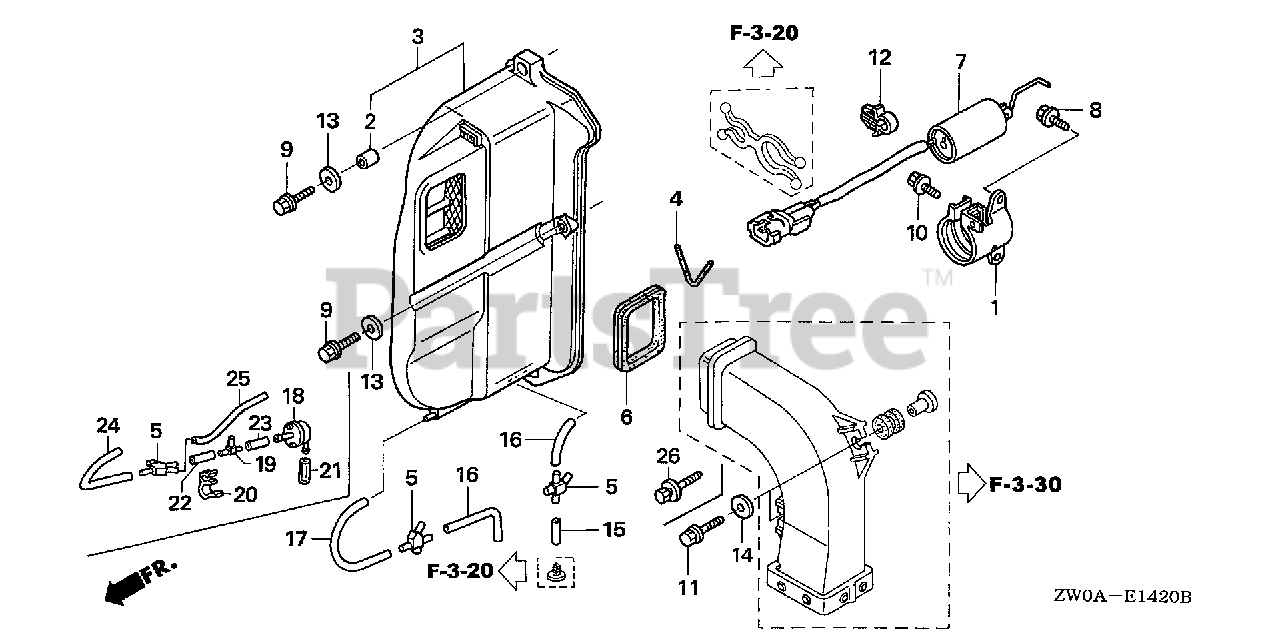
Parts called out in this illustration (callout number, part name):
2	COLLAR, DISTANCE
3	COVER, MUFFLER
4	GASKET, MUFFLER COVER
5	JOINT, THREE WAY
6	GROMMET, MUFFLER DUCT
9	BOLT, FLANGE (6X25)
11	BOLT, FLANGE (6X25)
13	WASHER, PLAIN (6MM)
14	WASHER, PLAIN (6MM)
18	CHAMBER, DRAIN
19	JOINT, MUFFLER DRAIN
20	CLAMP, TUBE (7.5-11.5) (BLACK)
21	BULK HOSE, VINYL (4X7X8000) (4X7X40)
22	BULK HOSE, VACUUM (4.5X1000) (4.5X35)
23	BULK HOSE, VACUUM (4.5X1000) (4.5X45)
24	BULK HOSE, VACUUM (4.5X1000) (4.5X100)
25	BULK HOSE, VACUUM (4.5X1000) (4.5X240)
26	BOLT-WASHER (6X27) (CT200)
